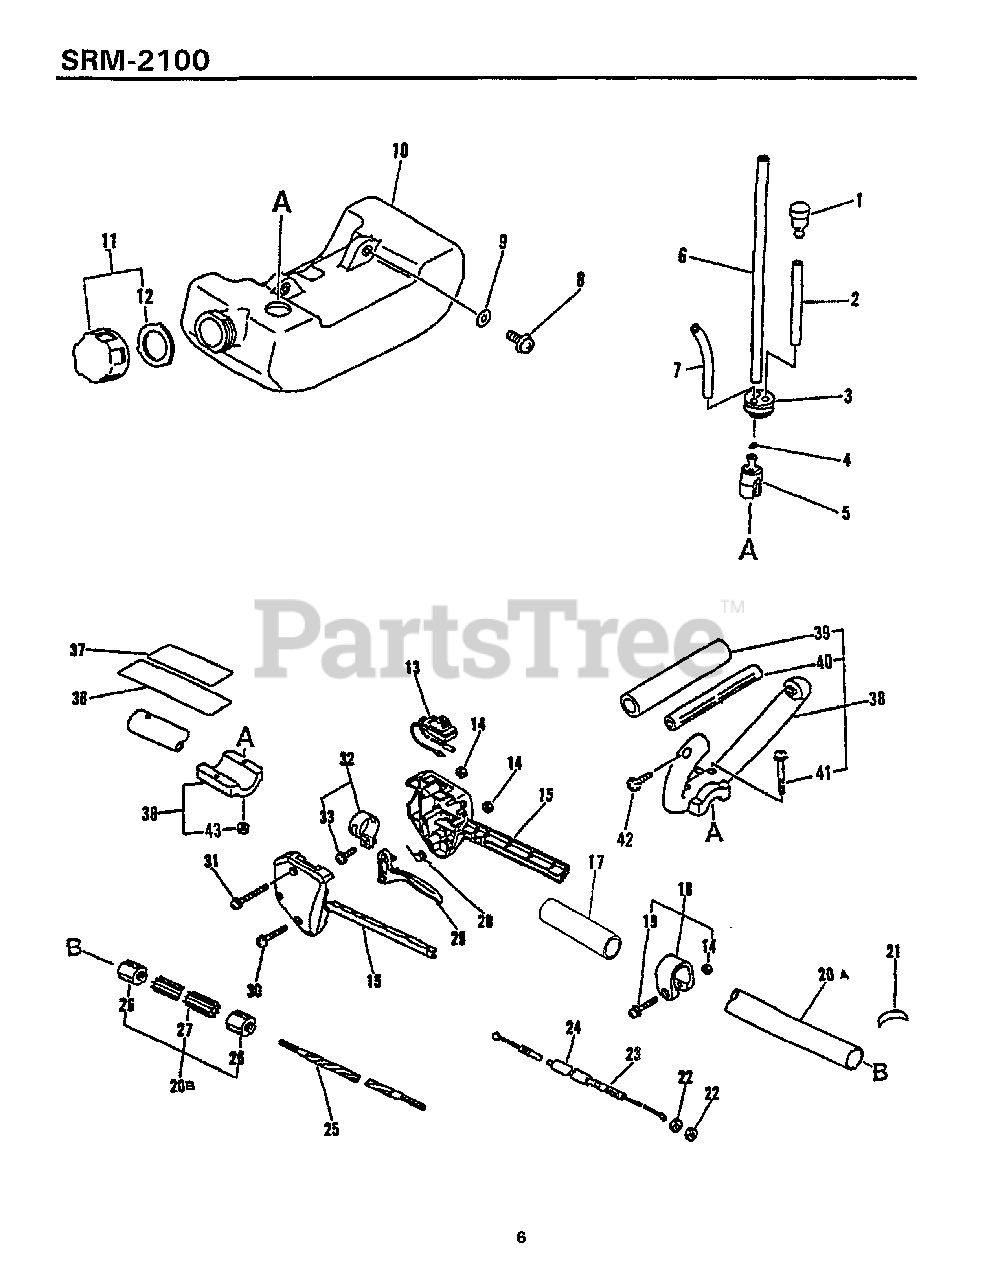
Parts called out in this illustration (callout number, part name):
1	Vent Asy
2	Pipe 3x5x70
3	Grommet, Fuel
5	Strainer, Fuel
6	Pipe, Fuel 3x5x180
7	Pipe 3x5x90
8	Screw 5x16
9	Washer 5
10	Tank, Fuel
11	Cap Asy, Fuel
12	Gasket, Fuel Tank Cap
13	Switch, Ignition
15	Bracket Set, Throttle
17	Grip, Front handle
18	Band 25
19	Screw 5x30
20	Housing Asy, Driveshaft
21	Label, Caustion
22	Nut 6 (3)
23	Wire, Throttle
25	Shaft, Flexible
26	Fixture, Liner
27	Liner, Flexible
28	Spring, Throttle Return
29	Control, Throttle
30	Screw 5x25
31	Screw 5x35
32	Band
33	Screw 5x14
36	Label, Caustion
37	Label, Caustion
38	Handle Asy, Loop
39	Grip, Front Handle
40	Handle, Front
41	Screw 6x35
42	Screw 5x30
